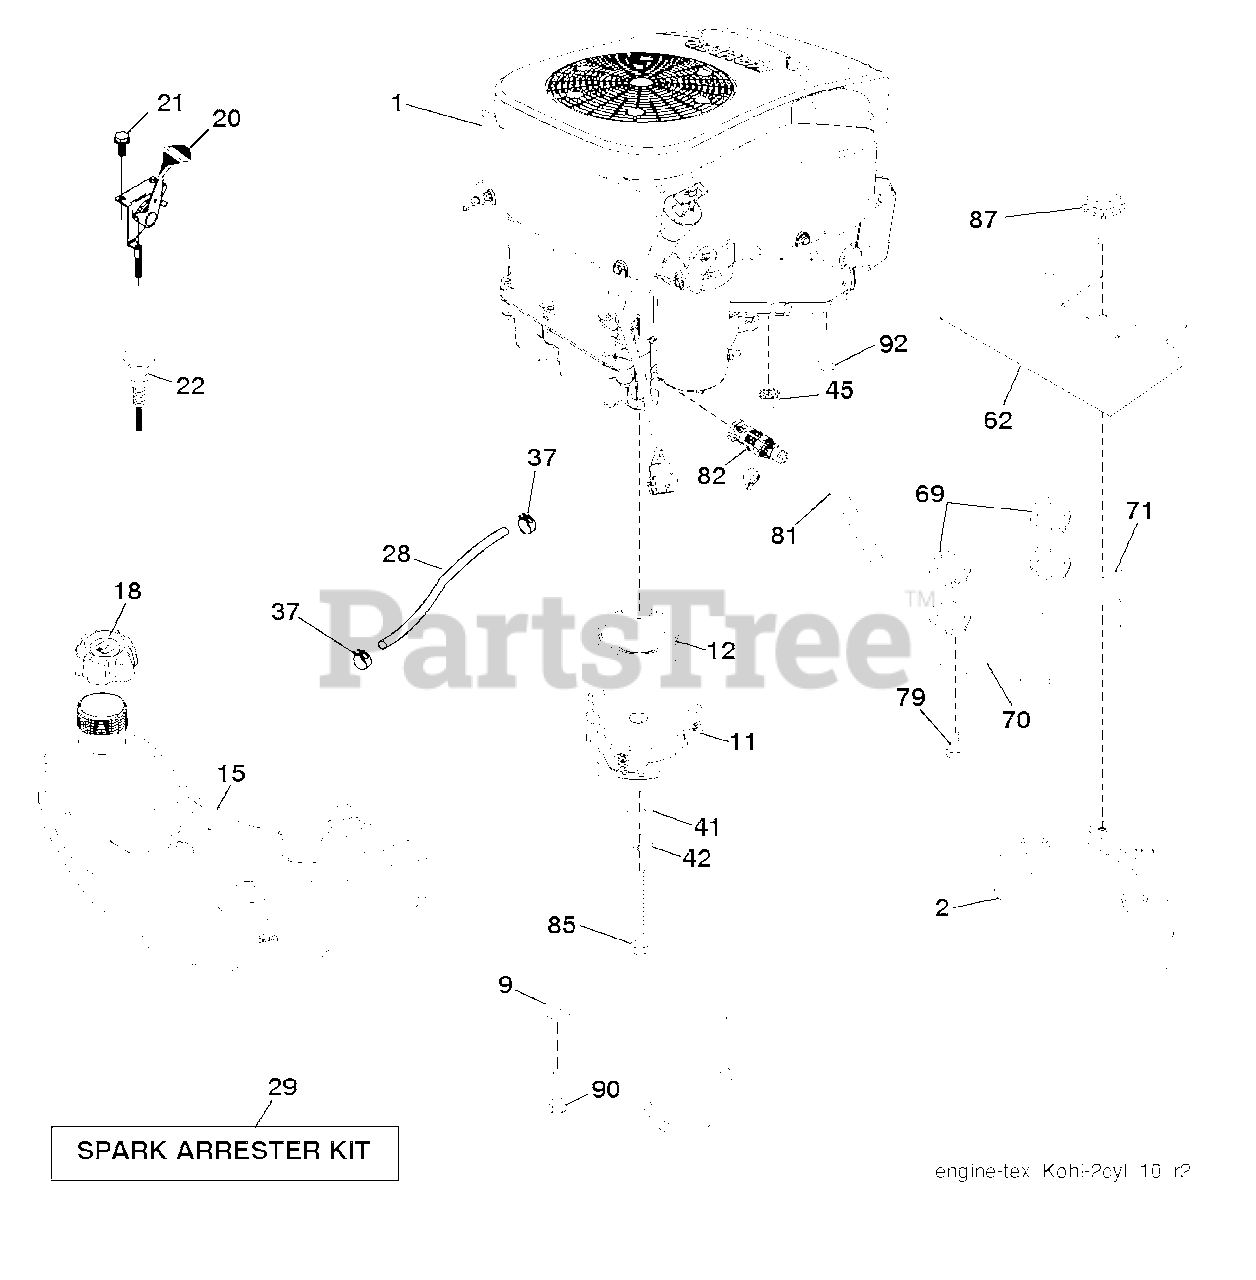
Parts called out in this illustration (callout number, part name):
2	MUFFLER.ASM.TWN.EXTNDED.DFLCTR
9	KEEPER.BELT.ENGINE.4.2
11	CLUTCH.ELECTRIC.LT.48"*
12	PULLEY.ENGINE.TUFFTORQ
15	TANK.ASSY.3.GAL.EPA
18	CAP.ASM.FL.RITCH.3"E10.SYM.498
20	THROTTLE CONTROL
21	SCREW.#10 X 0.750.BOS
22	CONTROL.CHOKE.ERGO.PUSH-IN.BLA
28	LINE.FUEL.64"REAR.EMIS
29	KIT.SPARK ARRESTOR 794945 B&S
37	HOSE CLAMP
42	LOCKWASHER
45	NUT
62	SHIELD.HEAT.MUFFLER
69	GASKET.EXHAUST.KOHL.CV18-CV26
70	RP.PIPE-EXHAUST LH
71	RP.PIPE-EXHAUST RH
79	SCREW.SOCKET HD.5/16-1
81	TUBE, DRAIN OIL ASM.
82	VALUE.OIL.DRAIN
85	BOLT HEX 7/16-20X4-1/4"
87	Bolt, 5/16-18 X 1-3/4
90	SCREW 3/8-16X1
92	SCREW 3/8-16X1
